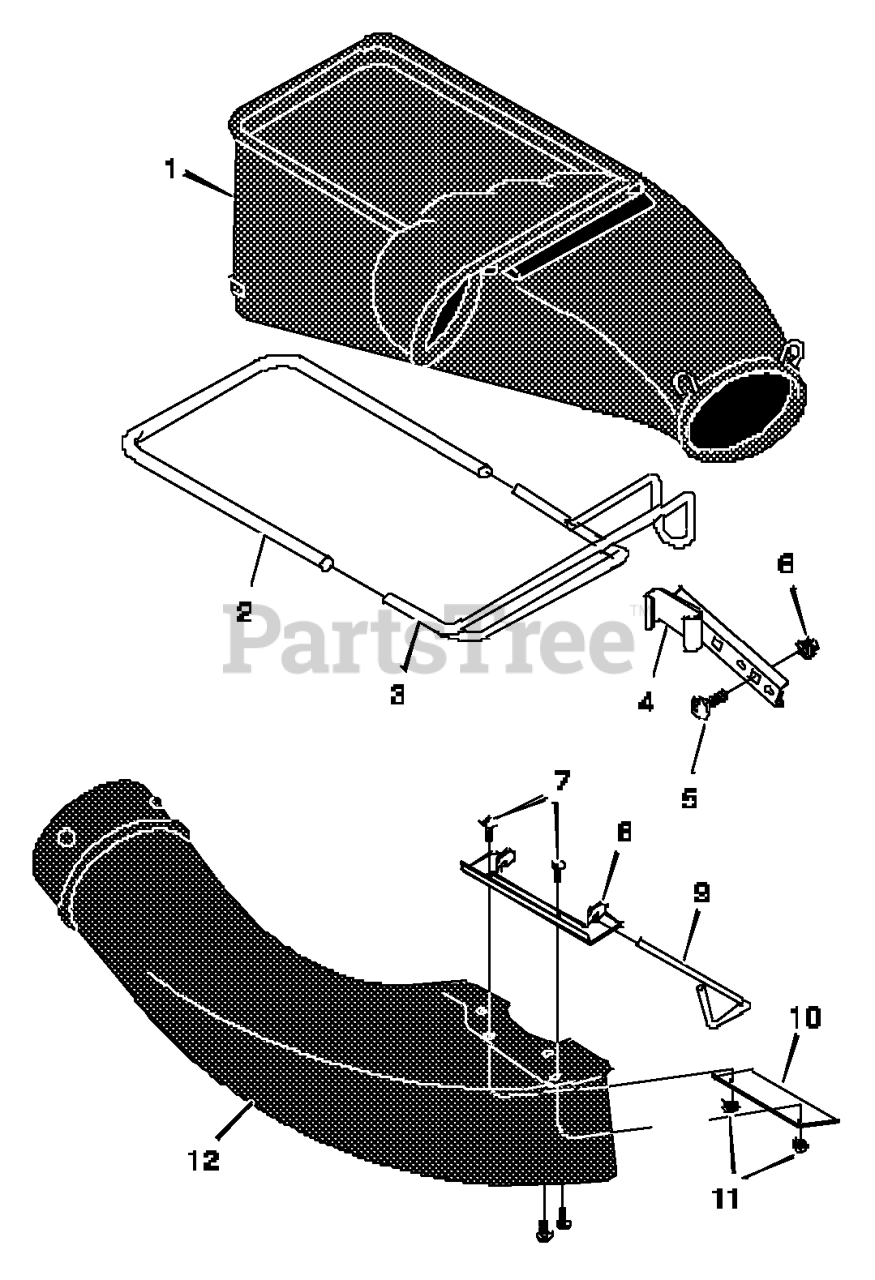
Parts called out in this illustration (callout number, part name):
1	Bag, Grass
2	Tube, Support
3	Frame, Bag
4	Bracket, Handle
5	Bolt, Carriage
8	Bracket, Chute
9	Pin, Locking
10	Plate, Inside
12	Extension, Chute
